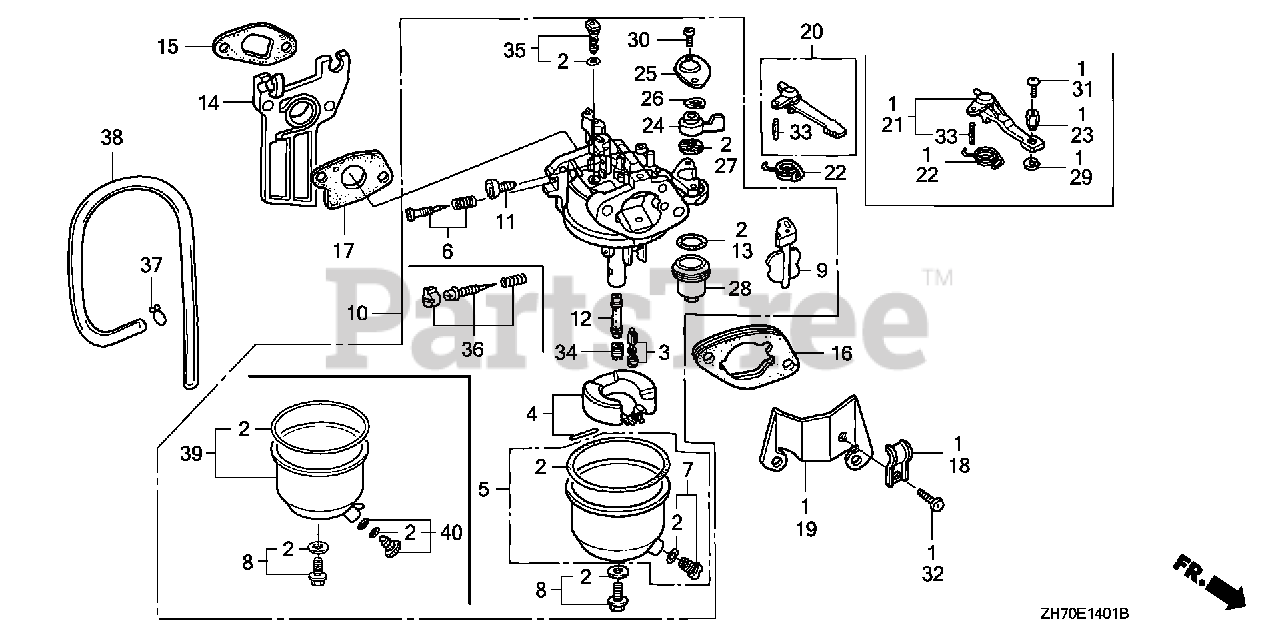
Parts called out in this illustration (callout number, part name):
2	GASKET SET
3	VALVE SET, FLOAT (SEAT NOT INCLUDED)
5	CHAMBER SET, FLOAT (CARBURETOR NO.) (FOR BE12A C)
5	CHAMBER SET, FLOAT (CARBURETOR NO.) (FOR BE12A A)
7	SCREW SET, DRAIN
8	SCREW SET
9	CHOKE SET (CARBURETOR NO.)
10	CARBURETOR ASSY. (BE60C B)
11	SCREW, THROTTLE STOP
12	NOZZLE, MAIN (CARBURETOR NO.)
12	NOZZLE, MAIN
13	GASKET, FUEL STRAINER CUP
14	INSULATOR, CARBURETOR
15	GASKET, INSULATOR
16	SPACER, CARBURETOR
17	GASKET, CARBURETOR
20	LEVER, CHOKE (STD)
24	LEVER, PETCOCK
25	PLATE, LEVER SETTING (CARBURETOR NO.)
26	SPRING, PETCOCK LEVER
27	GASKET, PETCOCK
28	CUP, FUEL STRAINER
30	SCREW, PAN (3X6)
30	SCREW, PAN (3X8) (CARBURETOR NO.)
33	PIN, SPRING (2X12)
34	JET, MAIN (#58)
34	JET, MAIN (#60)
34	JET, MAIN (#62)
35	JET SET, PILOT (#35) (CARBURETOR NO.)
36	SCREW SET, PILOT (CARBURETOR NO.)
